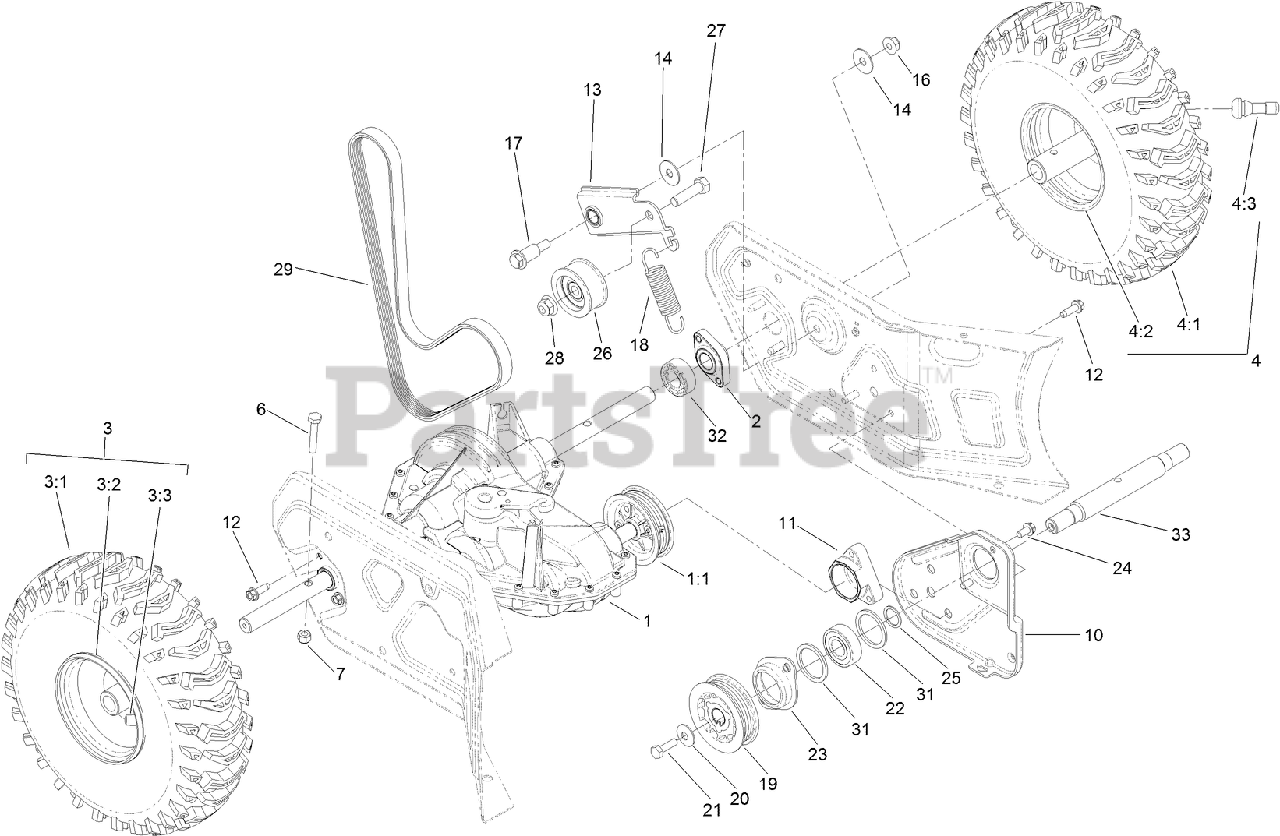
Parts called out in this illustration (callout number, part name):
1	TRANSMISSION
1:1	PULLEY REPAIR KIT
2	BEARING-AXLE
3	Loose Parts Package
4	Loose Parts Package
6	SCREW-HH
7	NUT-LOCK, NI
10	PLATE-SUPPORT, JACKSHAFT
11	SUPPORT-BEARING
12	SCREW-HWHTF
13	IDLER-TRACTION
14	WASHER
16	NUT-HF, NI
17	BOLT-SHOULDER, HHF
18	SPRING-EXTENSION
19	PULLEY-JACKSHAFT
20	WASHER-BELLEVILLE
21	SCREW-HH
23	RETAINER-BEARING
24	SCREW-HWH
25	WASHER-THRUST
27	SCREW-HH
28	NUT-HF, NI
31	WASHER-RUBBER
32	SPACER-AXLE
33	JACKSHAFT
